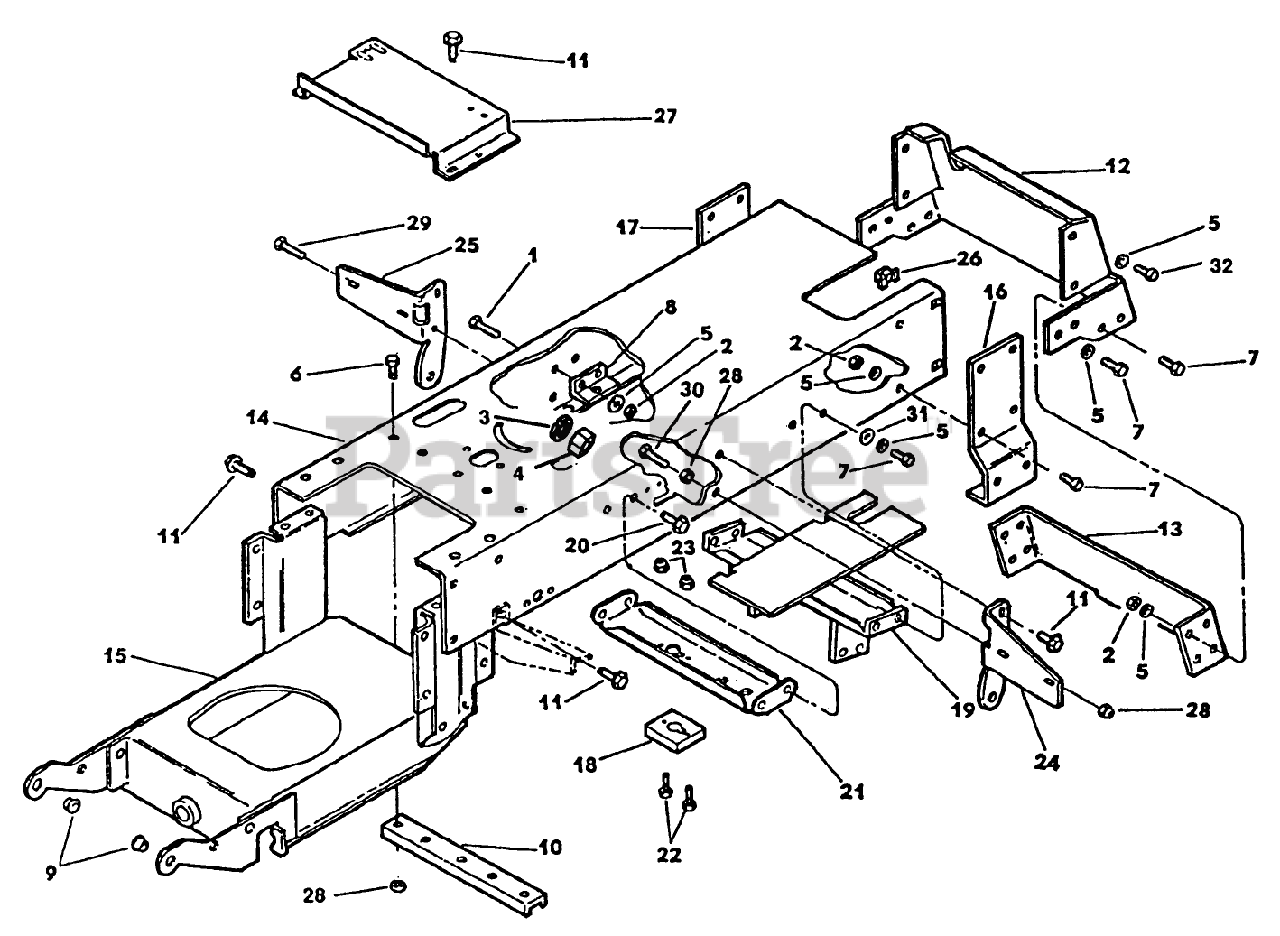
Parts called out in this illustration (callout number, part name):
2	NUT
4	NUT SS
5	WASHER
9	BEARING-NYLINER
18	BRACKET-SUPPORT *B
21	SUPPORT *B
22	SCREW
23	NUT-LOCK, CONE
25	SUPPORT - RH
27	SUPPORT, BATTERY *B
28	NUT
29	SCREW - HEX
